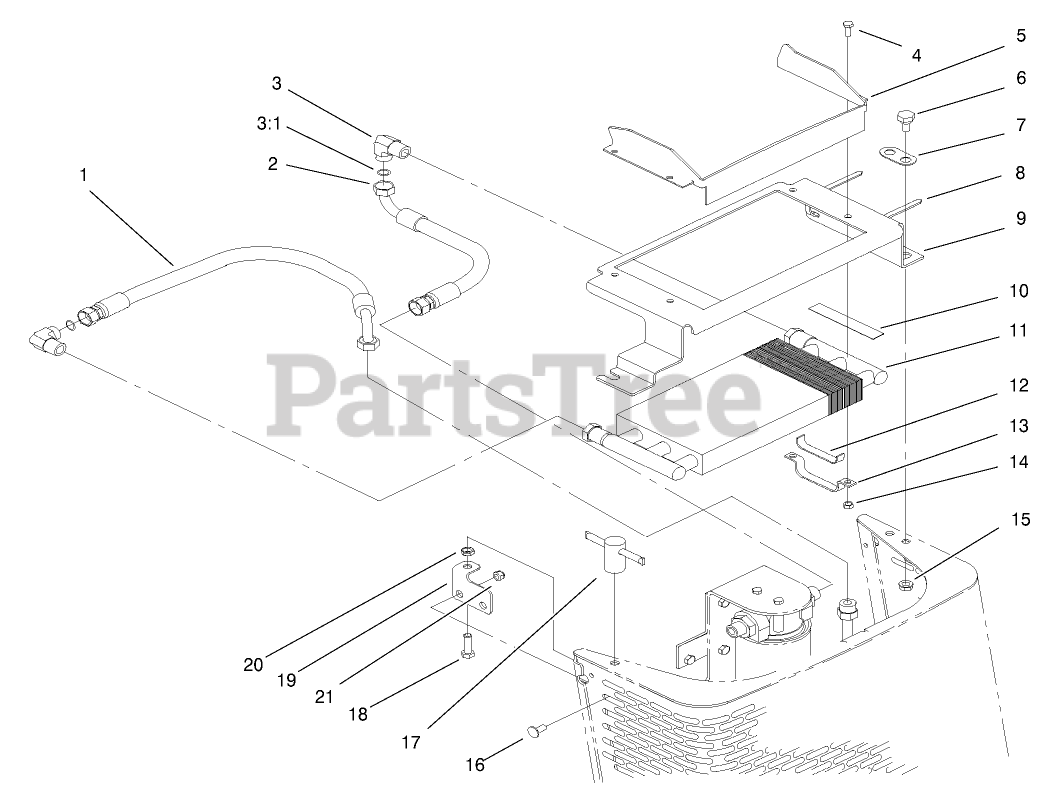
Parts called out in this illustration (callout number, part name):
1	HYD HOSE ASM
2	HOSE-HYD
3	ADAPTER-ELBOW, 90 DEG
3:1	O-RING
4	SCREW-HH
5	SHIELD-COOLER
6	BOLT-SHOULDER
7	WASHER-PIVOT
8	TIE-CABLE
9	BRACKET-COOLER
10	PAD-FOOTREST
11	COOLER ASM
12	PAD-SUPPORT
13	SUPPORT-COOLER
14	NUT-LOCK, NI
15	NUT-LOCK, NI
16	SCREW-CARR
17	HOLDDOWN ASM
18	SCREW-HH
19	BRACKET-HOLDDOWN
20	NUT-JAM
21	NUT-LOCK, NI
